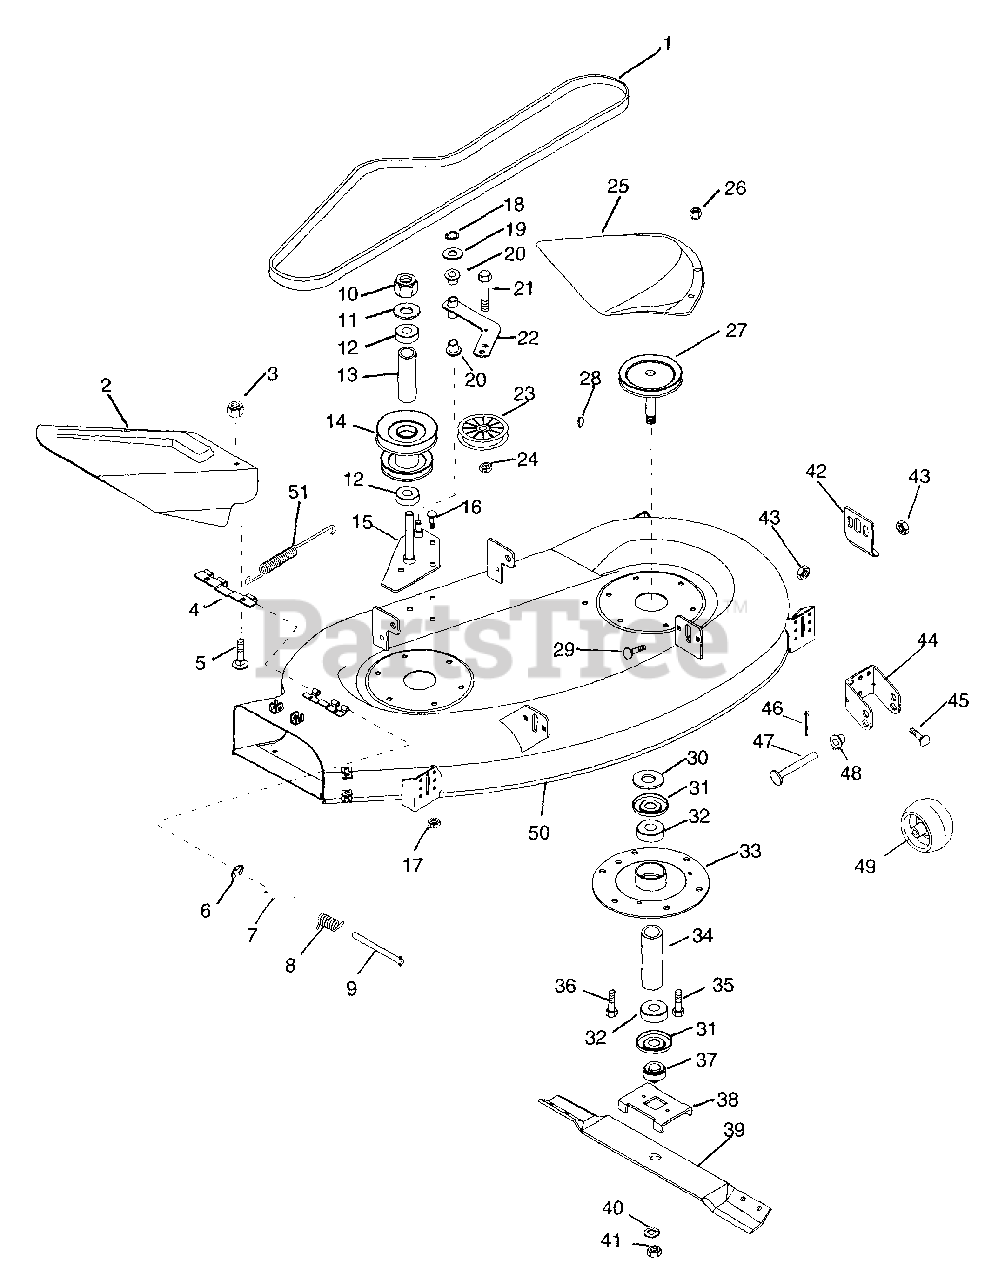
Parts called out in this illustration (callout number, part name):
1	V-BELT, 4L-WRAPPED
2	40IN. CHUTE DEFLECTOR
3	NUT-LK-CTR .250-20 PL
4	HINGE PLATE
5	BLT-RDHDSQNK .25-20X.75 GR5PL
6	RG-RTNG-EXT .312X.025
7	BSHG-SLV .334 X .502 X 1.437
8	SG-TORS .095X.50X 1.0
10	NUT-LK-NYL.625-18 PL
11	WSHR-FL-STL .640X1.005X.062 PL
12	BRG-BALL .625X1.375X.44
13	SPACER .640X.880X2.545
14	JACKSHAFT PULLEY
15	MOUNT PLATE
16	BLT-RDHDSQNK .312-18X.62SHTPL
17	NUT-FLG. .312-18 PL
18	RG-RTNG-EXT .500X.042 (E)
19	WSHR-FL-STL .505X.880X.072 PL
20	BSHG-FLG .500X.625X.187X.750FD
21	BLT-HEX .38-16X1.50 PL GR5
22	IDLER ARM
23	IDLER-FLAT 3.00X.38
24	NUT-LK TOP .375-16 GR C YWZC
26	NUT-LK-CTR .375-16 GR A PL
27	L. SPINDLE SHEAVE
27	R. SPINDLE SHEAVE
28	KEY-WDRF .188X.625X.31 SAE9MOD
29	BLT-RDHDSQNK.31-18X.75GR5SHTPL
30	WSHR-FL-STL .755X1.250X.125
31	BEARING SLINGER
32	BRG-BALL .750X1.781X.61
33	SPINDLE HOUSING
34	SPACER .753X1.000X1.140
35	BLT-HEX .38-16X.75 PL GR5
36	BLT-HEX .38-16X1.00 PL GR5
37	RETAINER HUB
38	BLADE TRAY 48
40	WSHR-LK .750X.188 MED PL
41	NUT-JAM .75-10 PL
42	MOWER ADJUSTMENT TAB
43	NUT-FLG. .312-18 PL
44	ROLLER CLEVIS
45	BLT-RDHDSQNK .312-18X.62SHTPL
46	PIN-COTR .15 X 1.0 PL
47	PIN-CLEV .371X3.25 YWZC
48	BSHG-FLG .372X.500X.312X.625NY
50	40" PAN WELDMENT
51	SG-TENS .113X.812X7.00
